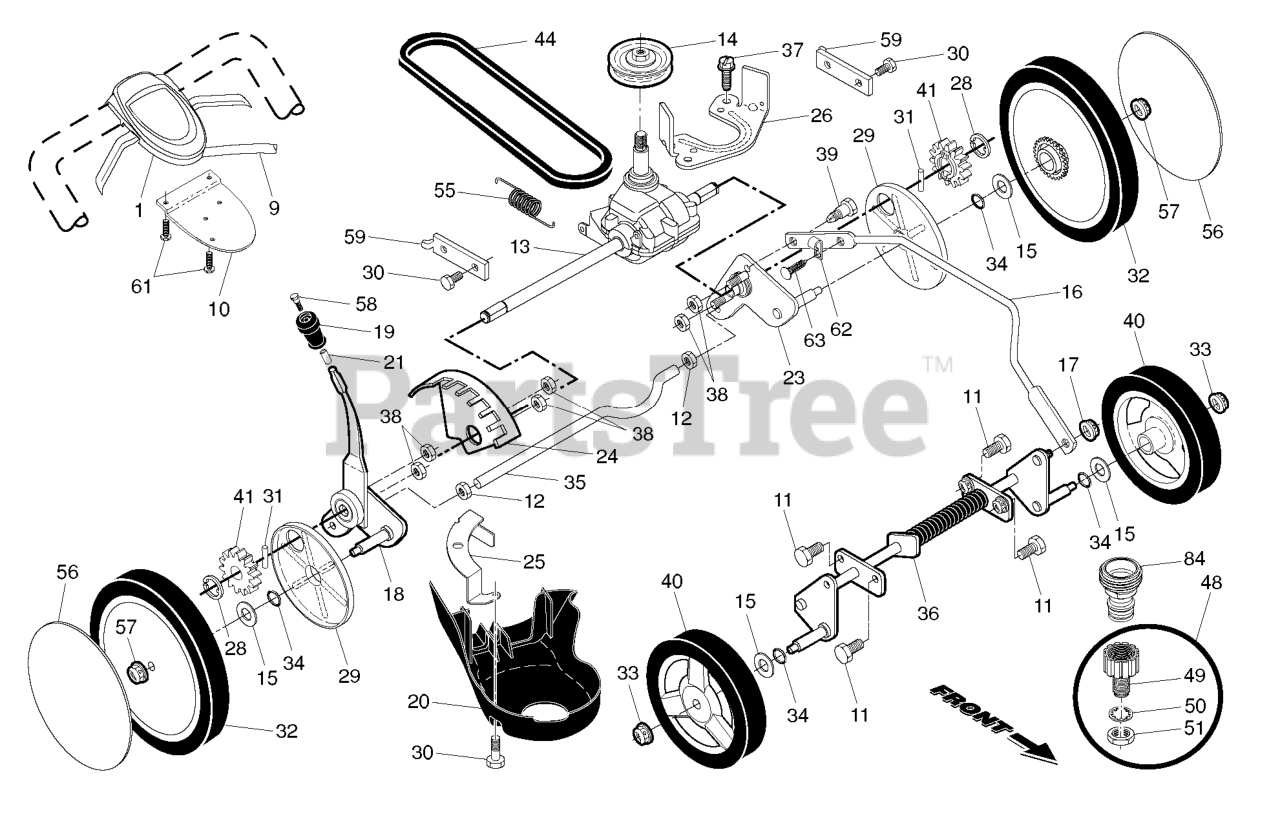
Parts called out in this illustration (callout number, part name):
1	RB CTRL.AW2.22+RGD.BS.GRY/BLK
9	CABLE.CONTROL.22RGD.GEN2
10	BRACKET.DRIVE.CONTR.GEN2.BLACK
12	NUT.HEX.1/2-20
13	RP TRANSMISSION.22+.RGD.AW2/
15	WASHER.FLAT.1/2
16	ROD.CONNECTING.RGD.22+.HW.BLAC
17	NUT.LOCK.5/16-18
18	KIT.SEL.ASM.22+HI-WHEEL.ZINC
19	KNOB.SEL.SPRING.22+.SP.RIB.BLK
20	COVER.BELT.22.RGD
21	SCREW.PLASTIC.ANCHOR.5/16
23	ADJUSTER.ARM.ASM.AX.LT.SP.HW
24	BRACKET.WHL.ADJ.9.POS.W/PAD
25	BRACKET.DRIVE.COVER.RGD.BZP
26	BRACKET.TRANS.BELT.KEEPER.BZP
28	E-RING 7/16 RE
29	COVER.DUST.WHEEL.RGD.HW
30	BOLT.5/16HEX.WHS.HD
31	PAWL, DRIVE
32	WHEEL.11.ALPHA.GRY.EXT.BB2
33	NUT.HEX.FLANGE.3/8-16.LO(3 2)
34	O-RING..070X.487.NEOPRENE
35	AXLE.REAR.RGD
36	RP AXLE.ASM.FRONT.RGD.ZINC
38	NUT.HEX.FLANGE.1/4
39	SHOULDER BOLT SEMI GIMLET PT.
40	WHEEL.8IN.H3SPK.ALPHA.GRY.BB1
41	PINIION.14.TOOTH.RGD
41	PINION.12.TEETH.RGD.22+HW
44	BELT.DRIVE.RGD.PLUS
48	KIT.WASH-OUT.PORT
48	KIT.WASH-OUT.PORT.ZINC.WALK
49	FITTING, HOSE, WATER WASHOUT
49	WASHOUT.PORT.ZINC.RGD.22+
50	WASHER.LOCK.INTERNAL.TOOTH
51	LOCKNUT.HEX.WITH.O-RING
56	HUBCAP.H.3SPK.GREY
57	NUT.HEX.FLANGE.3/8-16.LOCKNUT
58	SCREW.12-14X1.500
59	BRACKET.SUPPORT.22+RWGD.BZP
61	SCREW, PHILLIPS HEAD 10 X 5/8
62	CLIP.CABLE.BLK
63	FASTENER.PUSH.O.250X0.783
84	COUPLING.QUICK CONNECT
